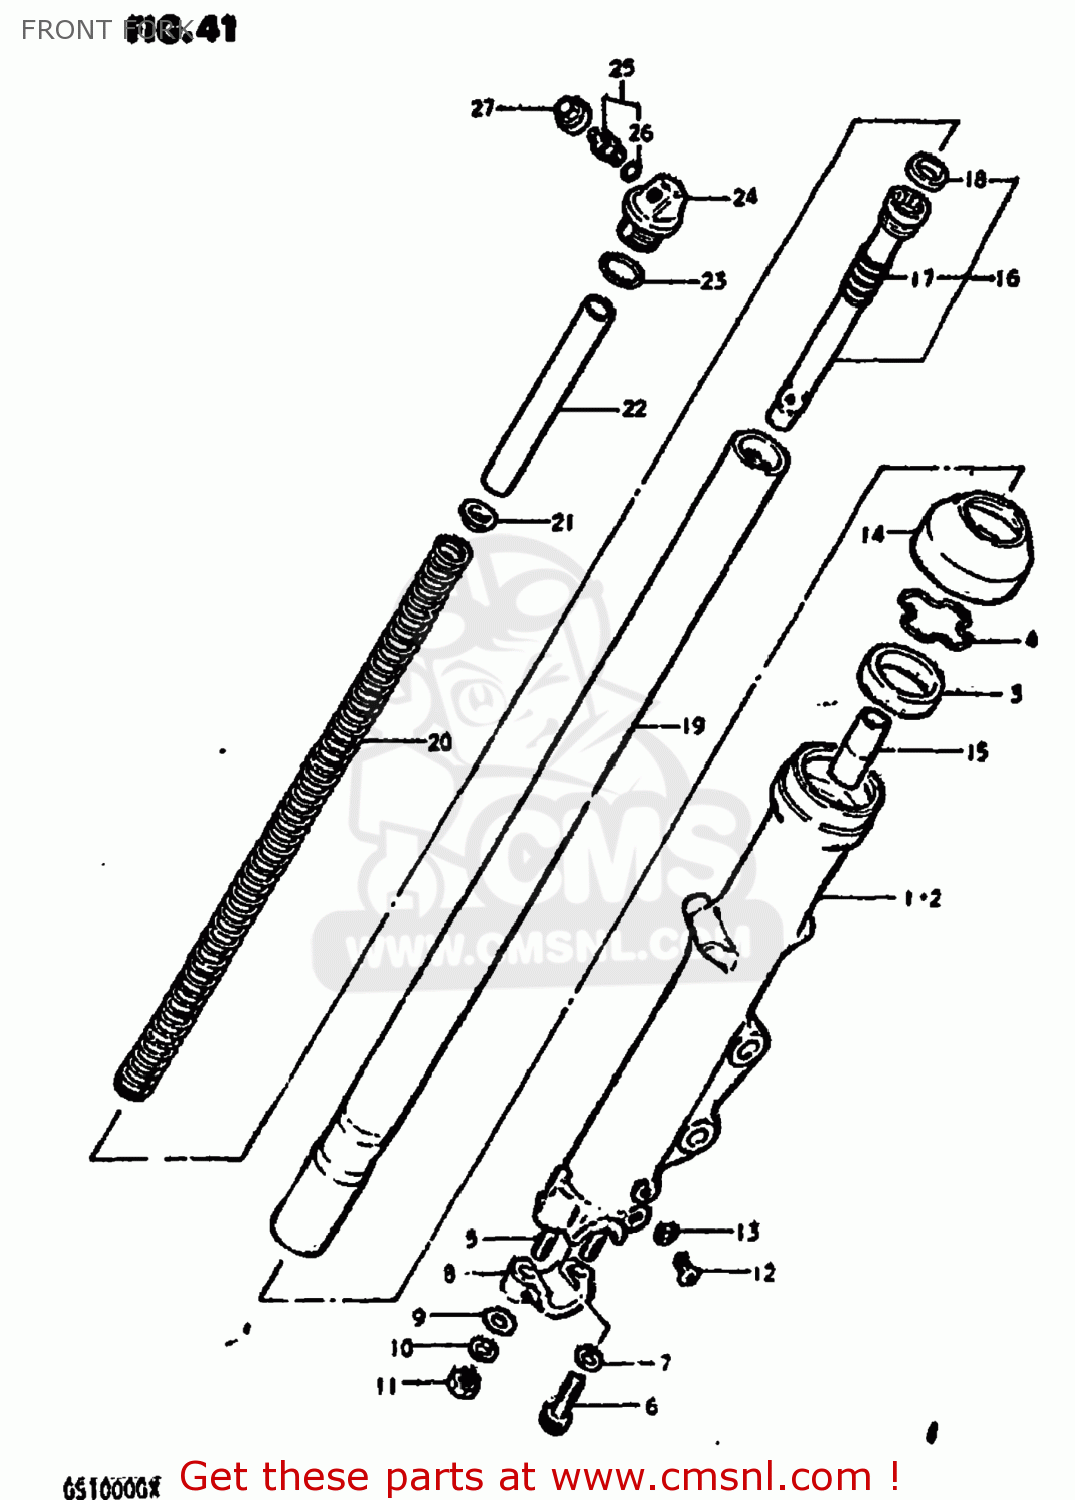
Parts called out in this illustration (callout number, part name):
0	DAMPER ASSEMBLY,LEFT
1	TUBE,FORK,OUTER,RIGHT
2	TUBE,FORK,LEFT,OUTER
3	OIL SEAL,FRONT FORK
4	RING,STOPPER
5	STUD BOLT
6	BOLT,FORK CYLINDER(10X25)
7	GASKET (NAS)
8	HOLDER,AXLE
9	WASHER
10	LOCK WASHER
11	NUT (8MM)
12	SCREW
13	GASKET,DRAIN,PLUG (NAS)
14	SEAL,DUST
15	PIECE,OIL LOCK
16	CYLINDER,FRONT FORK
17	SPRING,REBOUND
18	RING,PISTON
19	TUBE,FORK,INNER
20	SPRING,FRONT FORK
21	GUIDE,FRONT FORK SPRING C
22	SPACER,SPRING
23	O RING
24	CAP
25	VALVE
26	O RING
27	CAP,VALVE
